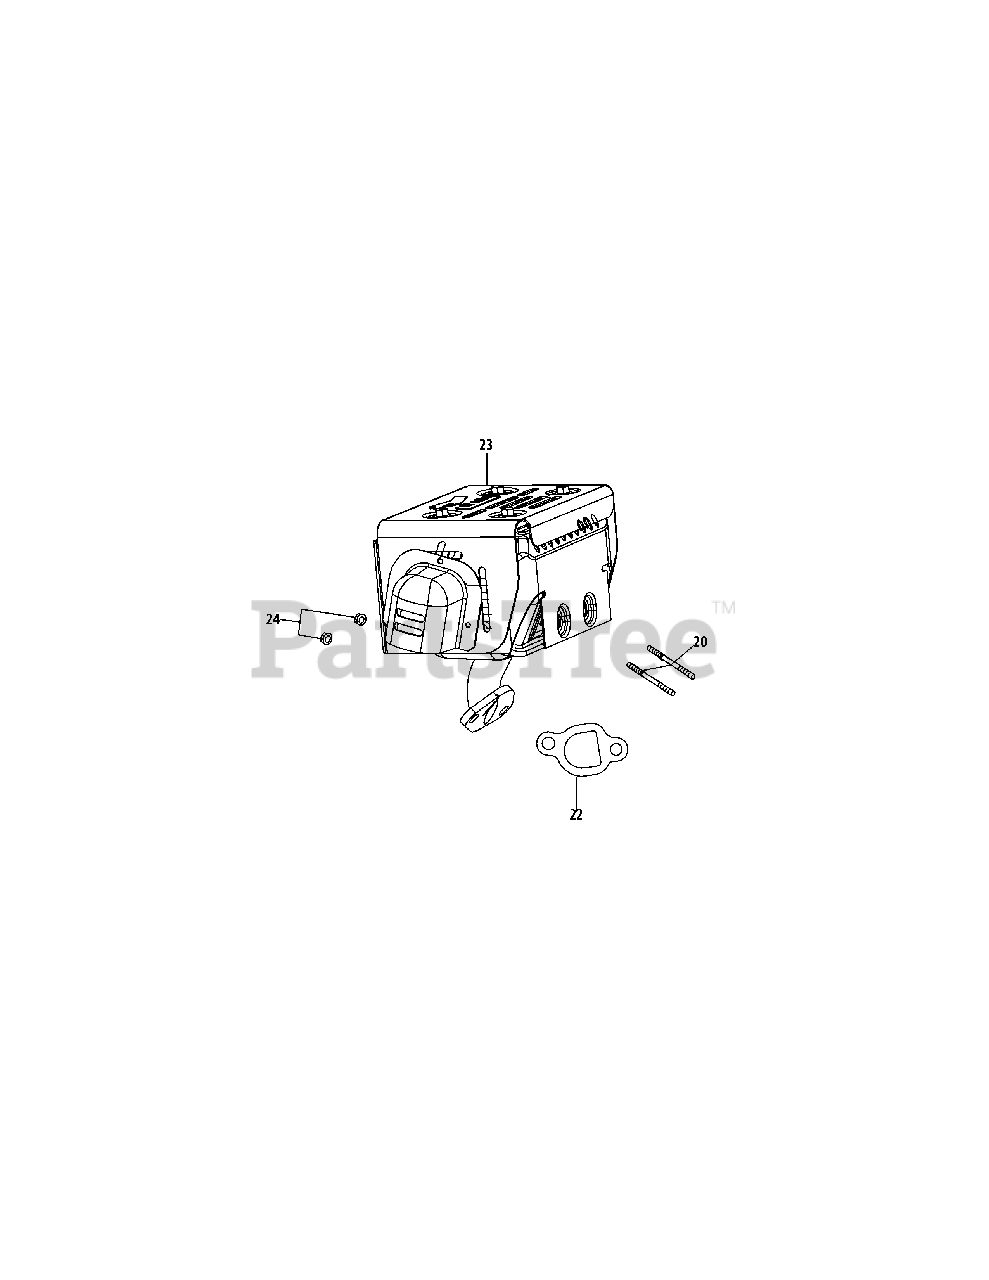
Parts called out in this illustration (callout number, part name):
20	Stud, M8×34, Exhaust
20	Muffler Stud Assemlby
22	Muffler Gasket
23	Muffler
24	Nut, M8
